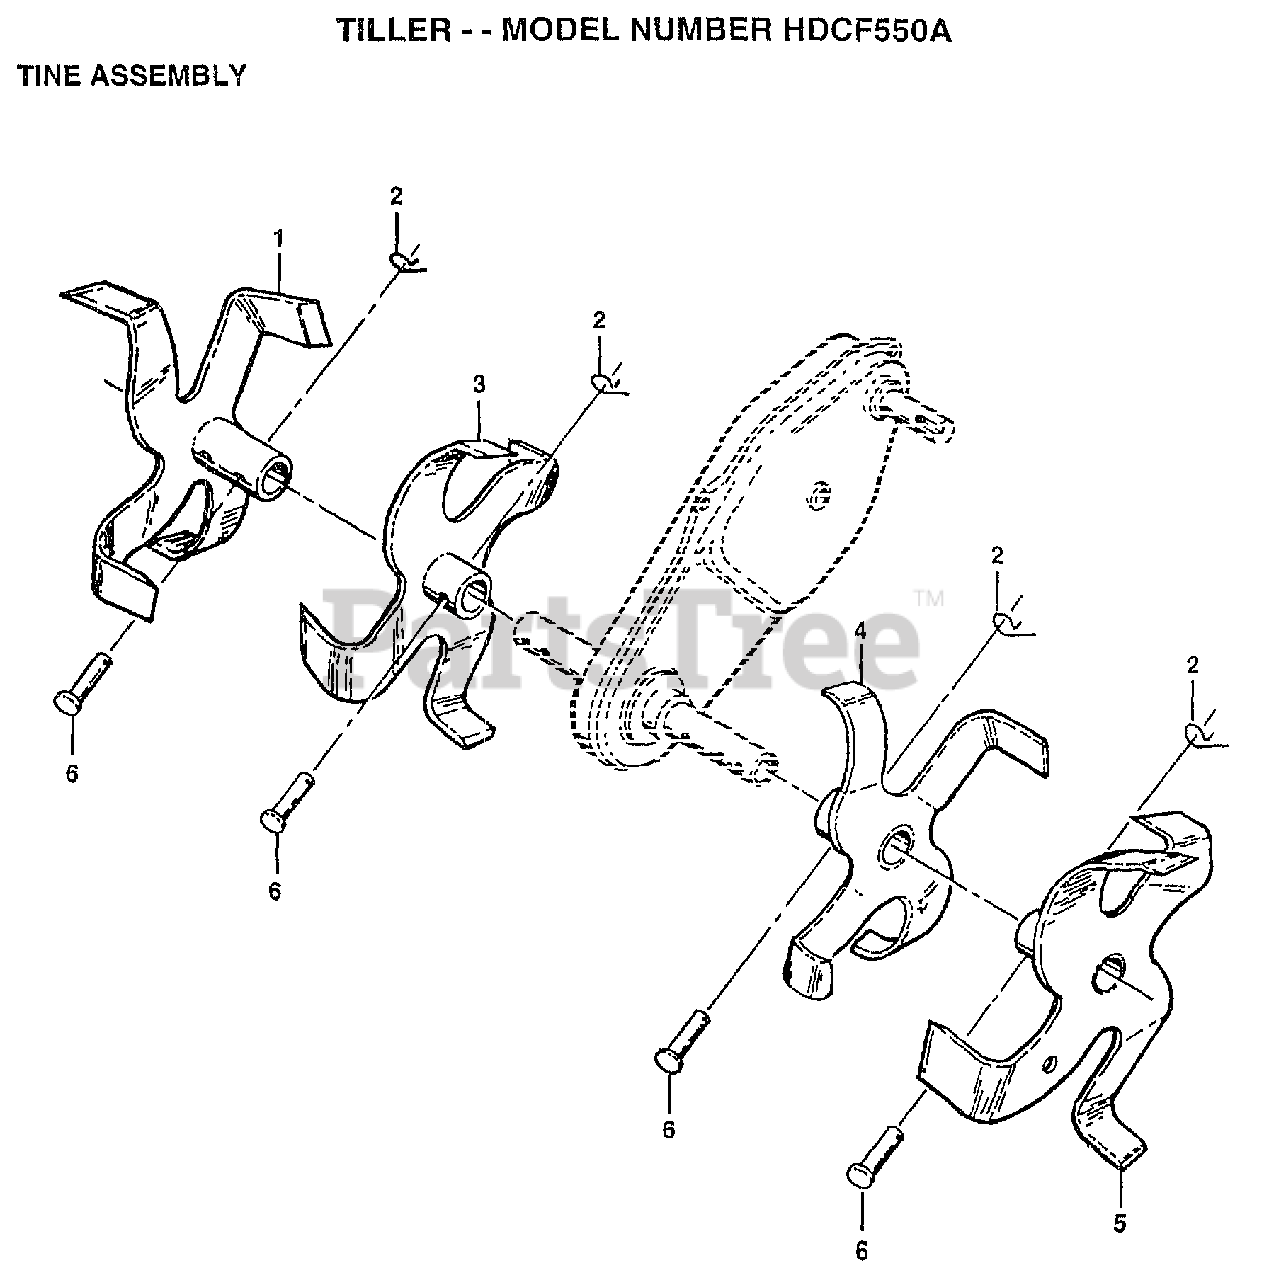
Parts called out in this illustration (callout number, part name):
1	TINE WELDMENT TI
2	RETAINER.SPRING
3	TINE TI
4	TINE, INNER, LH
5	TINE WELDMENT TI
6	RIVET.PAN HD.1.75
